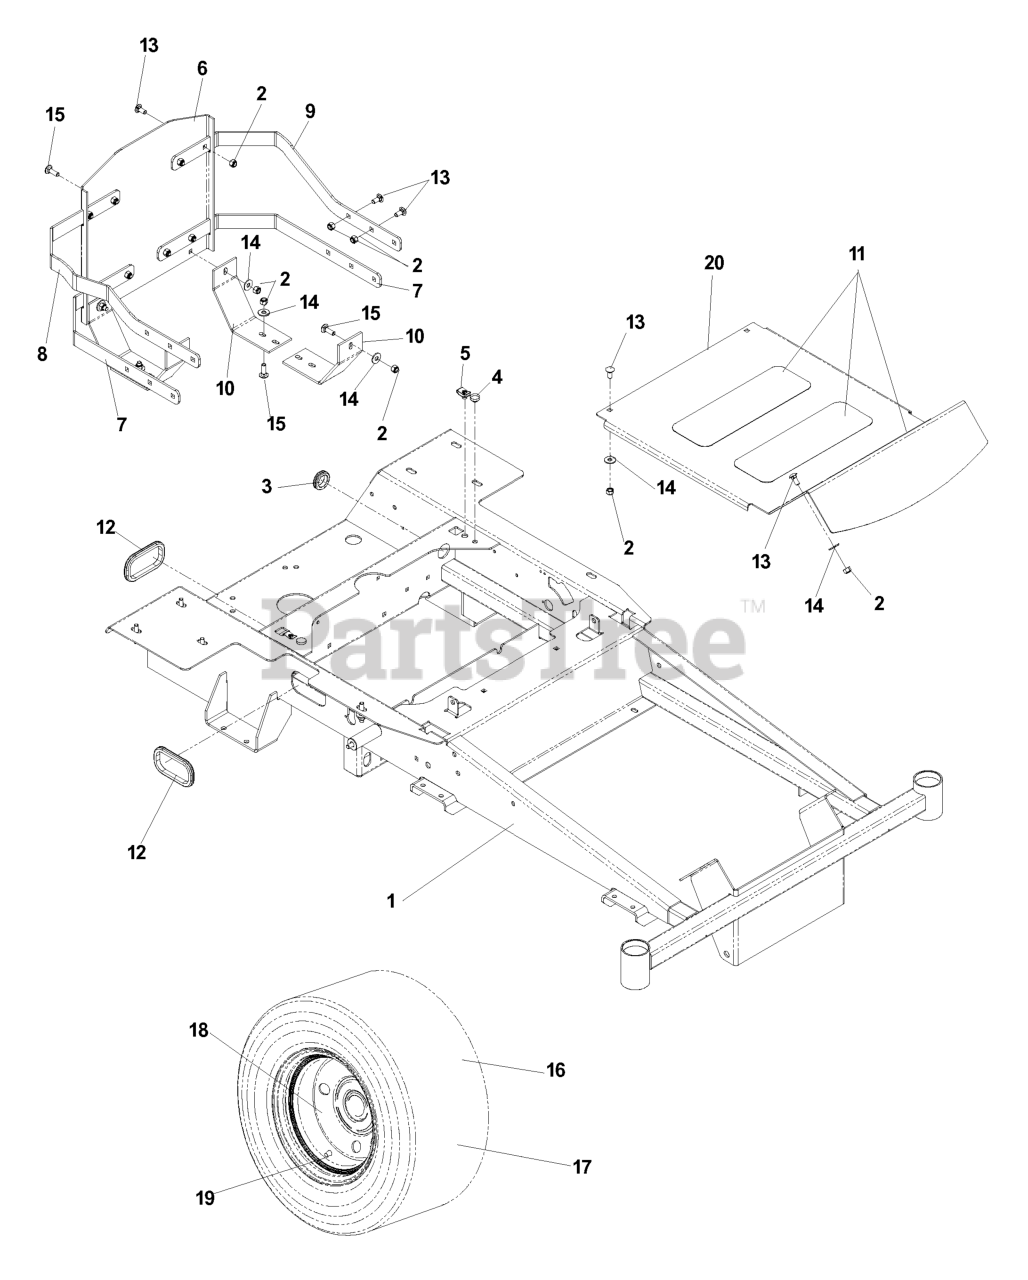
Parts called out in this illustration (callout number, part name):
1	FRAME W/DECALS #
1	FRAME W/DECALS 61"
2	NUT 5/16 NYLOC
3	RUBBER GROMMET
4	GROMMET, BUMPER
5	U-CLIP 5/16-18 NUT RETAINER
6	ENGINE GUARD
7	REAR GUARD STRAP, LOWER
8	REAR GUARD STRAP, UPPER RIGHT
9	REAR GUARD STRAP, UPPER LEFT
10	SKID PLATE
11	ANTI-SKID PAD
13	BOLT 5/16C X 3/4" CARRIAGE
14	WASHER 5/16 FLAT
15	RHSNB 5/16C X 1
16	TIRE/WHEEL ASM 18X9.5-8
16	TIRE ASM 18 X 8.5-8
17	TIRE 18 X 9.5 TURF RIDER
17	TIRE, 18 X 8.5, TURF RIDER
18	RIM.8X7.W/8".OFFSET.SILVER.ZTR
18	RIM.8X7.SILVER.ZTR
19	VALVE STEM TR-412
